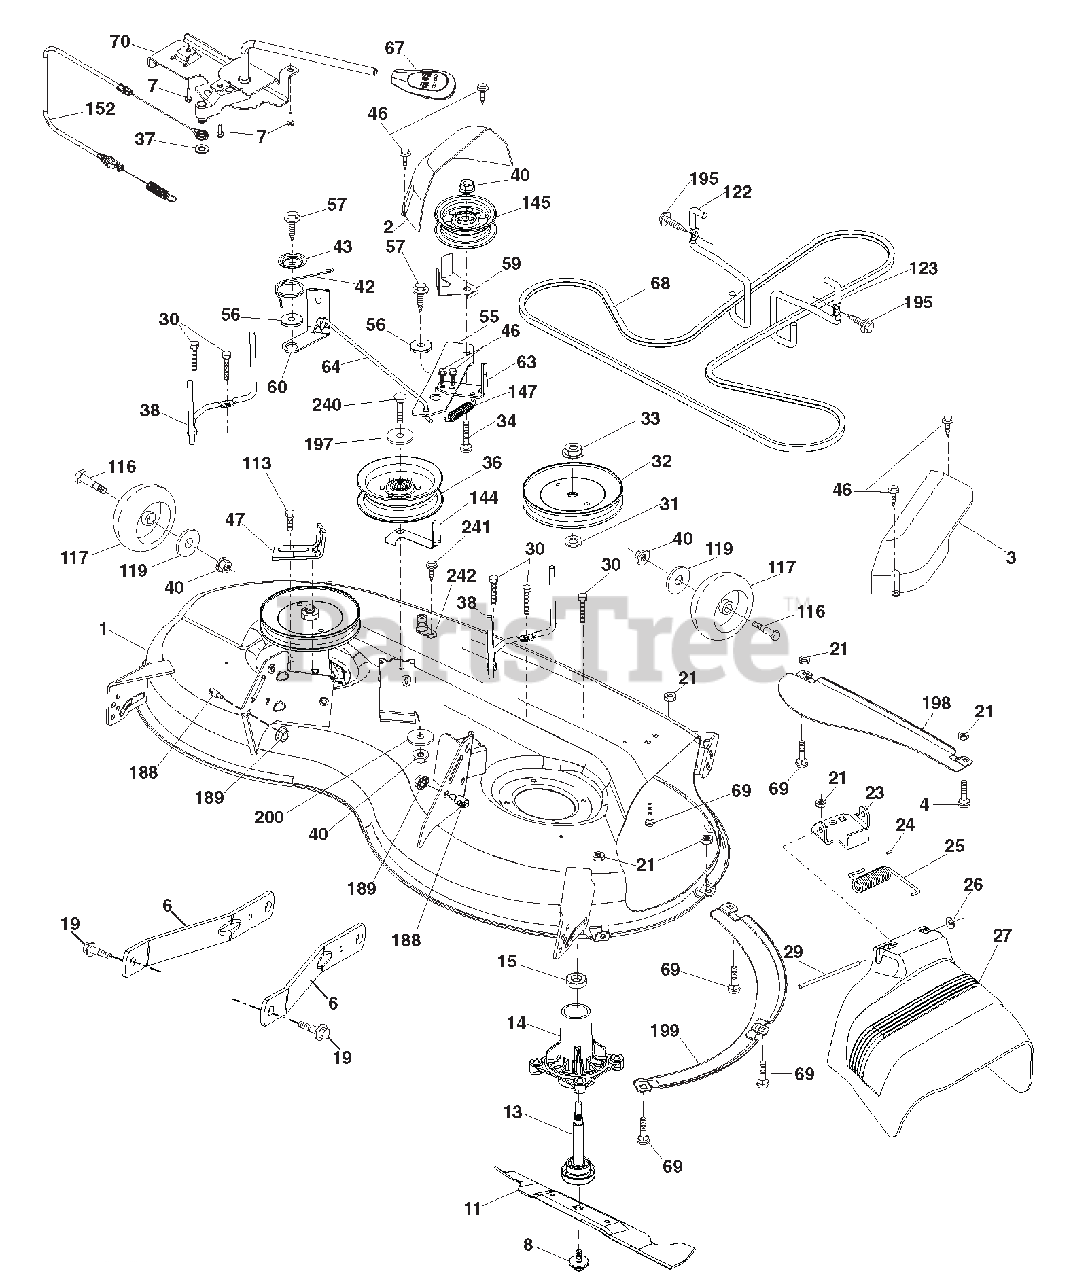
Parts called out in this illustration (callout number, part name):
1	MOWER HOUSING
2	COVER.MANDREL.LH.46"
3	COVER.MANDREL.RH.46"
4	BOLT.HEX.HD.1/4-20UNC X 3/4
6	ARM.SUSPENSION.MOWER.REAR.LD
8	BOLT/WASHER ASM.7/16-20.UNF
11	BLADE.MOWER.46"HI LIFT BAGGER
13	SHAFT ASM.MNDRL.N/GREASEABLE38
14	HOUSING.MANDREL.4PT.SERVICE
15	BEARING.BALL.MANDREL
19	BOLT.SHOULDER
21	Nut, Hex, Crownlock 5/16-18
23	BRACKET.DEFLECTOR.38/42"2005
24	CAP.SLEEVE..80X.112.BLK.MOWER
25	SPRING.TORSION.DFL.38/42/46.GR
26	NUT.PUSH.PHOS.& OIL
27	SHIELD.DEFLECTOR.MOWER 46"BLK
29	ROD.HINGE.42/46"
30	SCREW.THD ROLL.DOD PT.HEX
31	WASHER.SPACER.MANDREL
32	PULLEY.MANDREL.5.438 PD.42"
33	NUT.FLANGE.LOCK.TOP
34	BOLT.CARR.SH.3/8-16X1-1/2.GR5
36	PULLEY.IDLER.4.50.RAW
37	WASHER.13/32 X 13/16 X 16 GA.
38	KEEPER.BELT.MANDREL.PULLEY
40	Nut, Hex, Flangelock 3/8-16
42	SPRING.TORSION.BRAKE
43	SPRING.TORSION.RETAINER
46	SCREW.THD.ROLL.1/4-20 X 5/8
47	BRACKET.CLUTCH.CABLE
55	IDLER.ARM
56	SPACER.RETAINER
57	SCREW.3/8-16X1.SMGML.TAP/R.BLK
59	GUARD.TUV.IDLER
60	ARM.BRAKE.MOWER.38/46"LH.TEX
63	ARM.BRAKE.MOWER
64	LINKAGE ASM.BRAKE.CLEAR ZINC
67	HANDLE.CLUTCH.CABLE.LT TEX.428
68	V-BELT.DRIVE.MWR.MECHANICL.46"
69	BOLT.RDHD.SQNK.5/16-18 X 5/8
70	CLUTCH ASM.
113	BOLT.5/16-18HEX.WHS.HD.LCKSERR
116	BOLD SHLD "A" 2.41 "B" 1.66
117	WHEEL.GAGE.HALF.SPOKED
119	Washer 3/8 x 7/8 x 14 Ga.
122	KEEPER.BELT.ENGINE.LH.LT.TEX
123	KEEPER.BELT.ENGINE.RH.LT.TEX
144	KEEPER.BELT.MOWER
145	PULLEY.IDLER 48"PRIMARY
147	SPRING.RETURN.DECK.38/46"
152	CABLE.CLUTCH.MANUAL
188	STUD.FASTNER.W/'D'ANTI-ROTATIO
189	Nut, Lock Hex Flange 5/16-18 u
195	SCREW.HEXWSH THDR3/8-16X3/4.BL
197	Washer 13/32 x 13/16 x 12 Ga.
198	BAFFLE.CENTER.FRONT
199	BAFFLE.FRONT.RH
200	WASHER.13/32 X 1 X 1/2.11GAHRD
240	BOLT.FIN.HEX.3/8-16X 2-1/4 GR5
242	PORT WASHOUT
